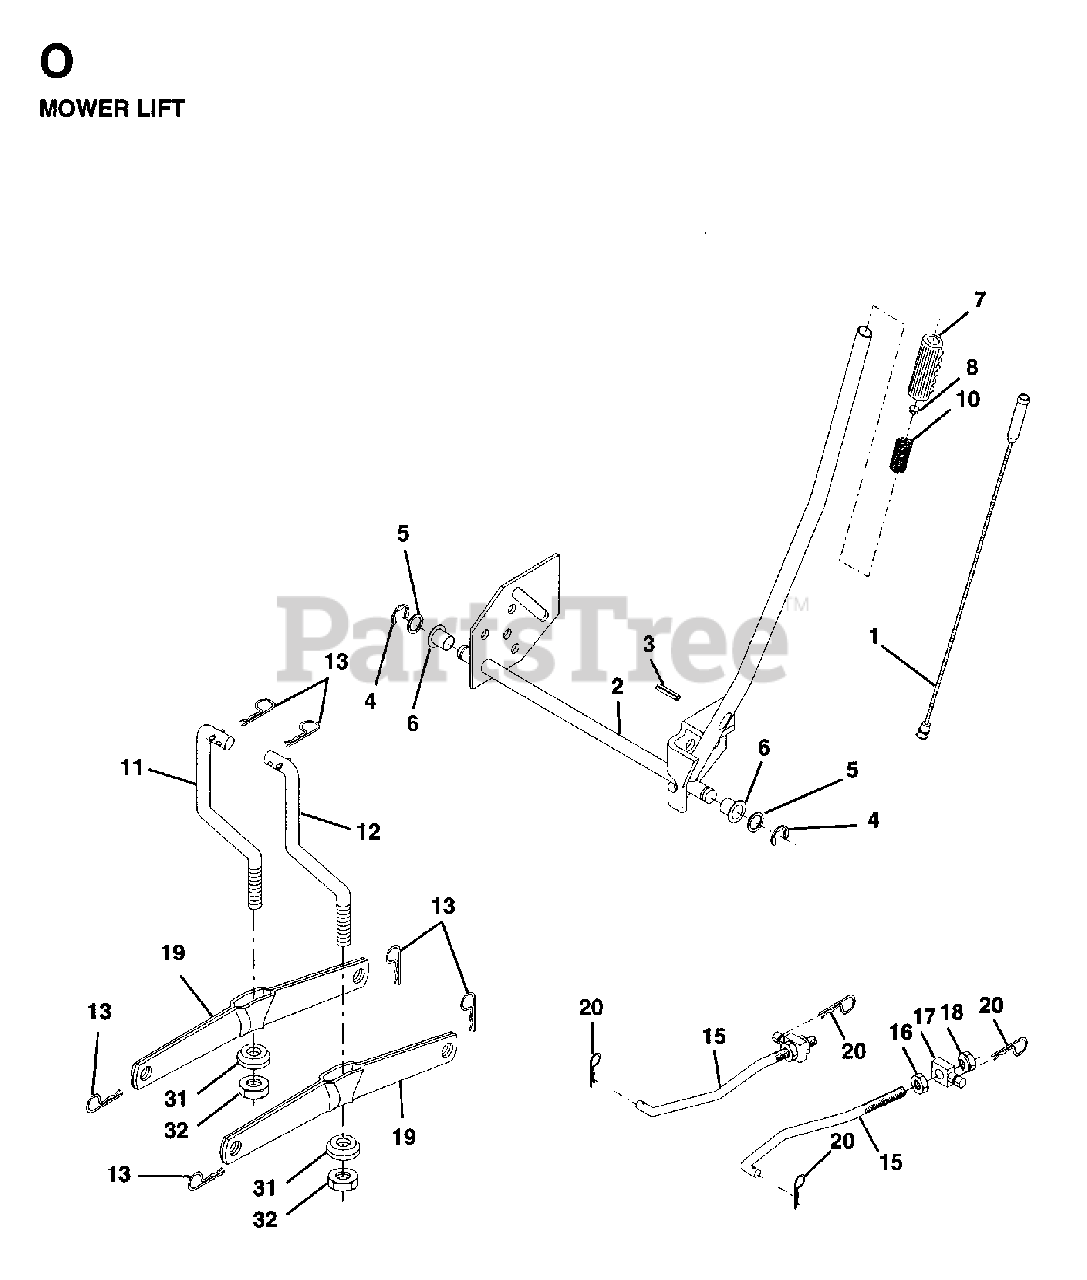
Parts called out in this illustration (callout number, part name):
1	WIRE, INNER HANDLE
2	SHAFT ARM LIFT RH
3	PIN GROOVE
4	RETAINING RING LT
6	BEARING.NYLON
7	GRIP
8	PLUNGER BUT KIT
10	SPRING, COMP T
11	LINK LIFT LH
12	LINK LIFT RH
13	RETAINER-SPRNG RB
15	FRONT LINK
16	NUT
17	TRUNION
18	NUT
19	ARM.REAR.SUSPENSION
20	SPRING RETAINER
31	BEARING PIVOT
32	NUT CROWNLOCK 3/8-24
